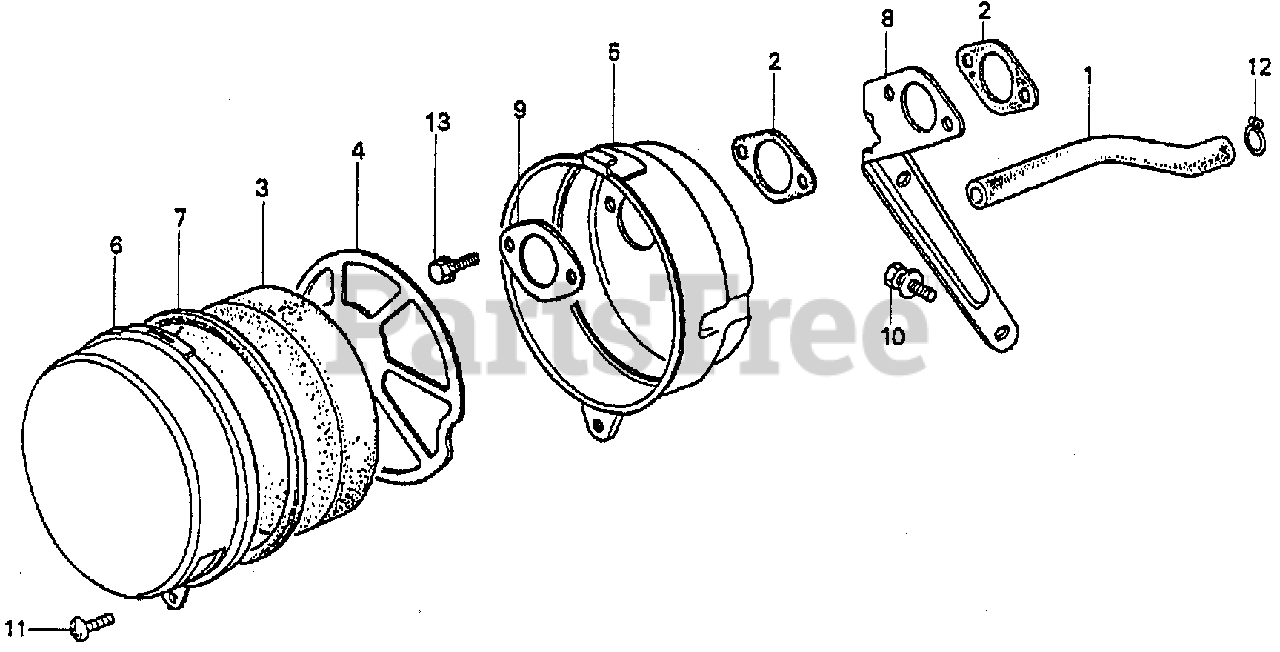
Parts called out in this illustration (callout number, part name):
1	TUBE, BREATHER
2	GASKET, AIR CLEANER (NOT AVAILABLE)
3	ELEMENT, AIR CLEANER
4	GRID, CLEANER
5	HOUSING, AIR CLEANER
6	COVER, AIR CLEANER *R8* (BRIGHT RED) (NOT AVAILABLE)
7	RUBBER, SEAL
8	STAY, CARBURETOR (NOT AVAILABLE)
9	PLATE, AIR CLEANER (NOT AVAILABLE)
10	BOLT-WASHER (8X16)
11	SCREW, PAN (6X12)
12	CLIP, TUBE (B12.5)
13	BOLT, FLANGE (6X16)
13	BOLT, FLANGE (6X20)
